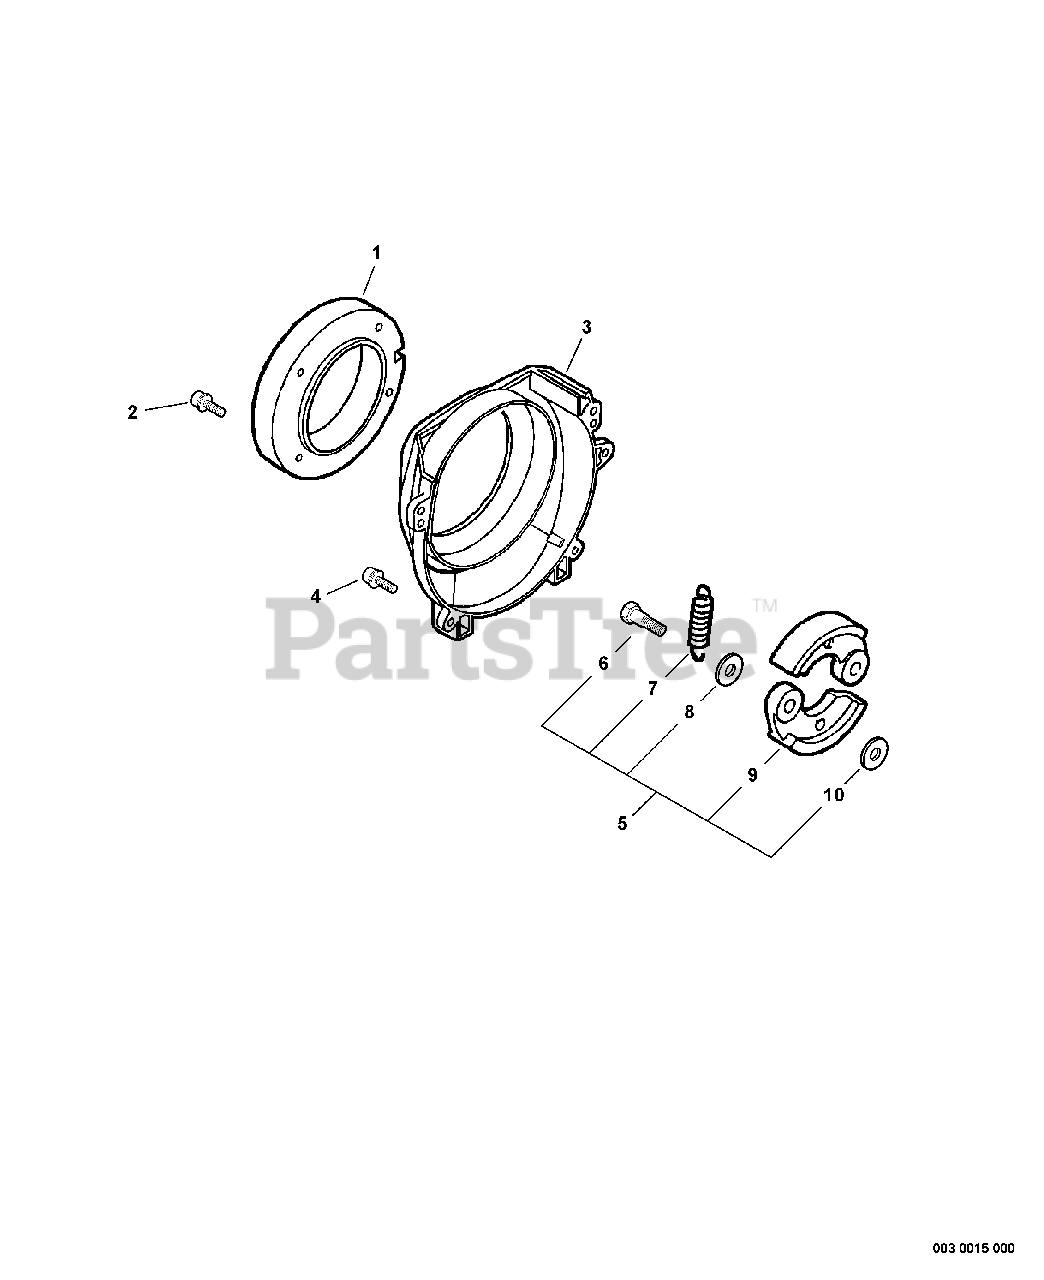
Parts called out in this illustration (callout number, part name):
1	PLATE, CLUTCH
2	SCREW - 5X20
3	CASE, FAN
4	SCREW - 5X20
5	CLUTCH ASSY
6	BOLT, CLUTCH
8	WASHER - SPRING
9	SHOE, CLUTCH
